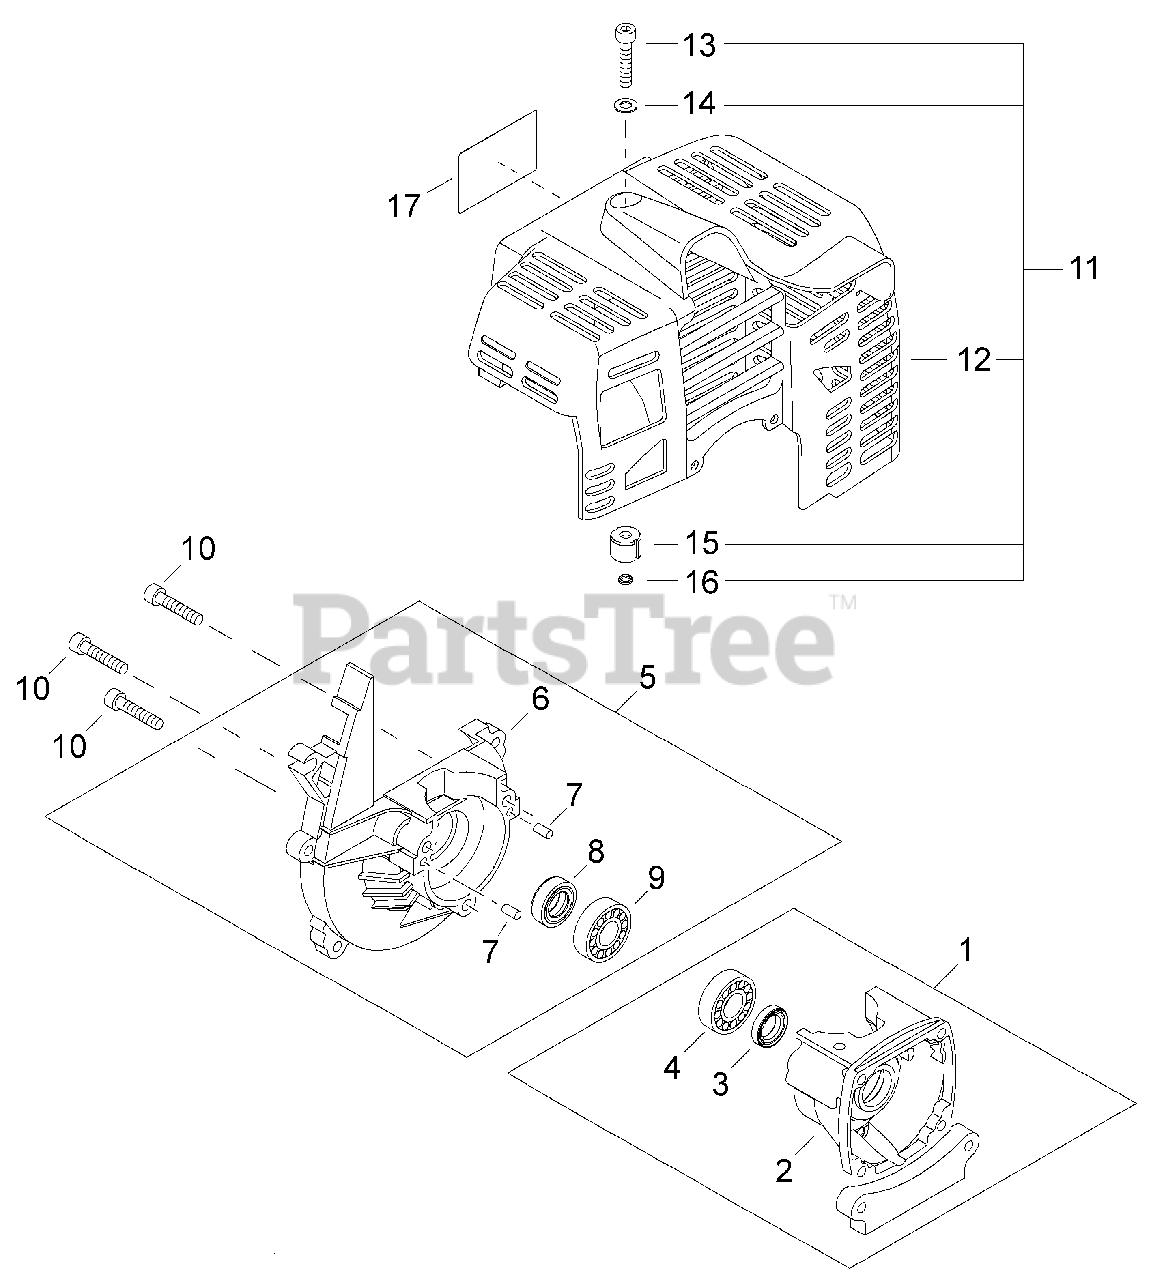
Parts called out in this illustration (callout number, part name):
1	CRANKCASE ASSY, S
2	CRANKCASE S
3	SEAL, OIL 12
4	BEARING, BALL 6001 C3
5	CRANKCASE ASSY, M
6	CRANKCASE M
7	PIN, LOCATING Ø4×8
8	SEAL, OIL 12
9	BEARING, BALL 6001 C3
10	BOLT 5×25
11	COVER ASSY, ENGINE
12	COVER, ENGINE
13	BOLT 5×25
14	WASHER 5.5×12×0.8
15	INSULATOR 5 MM
17	LABEL, AH231
